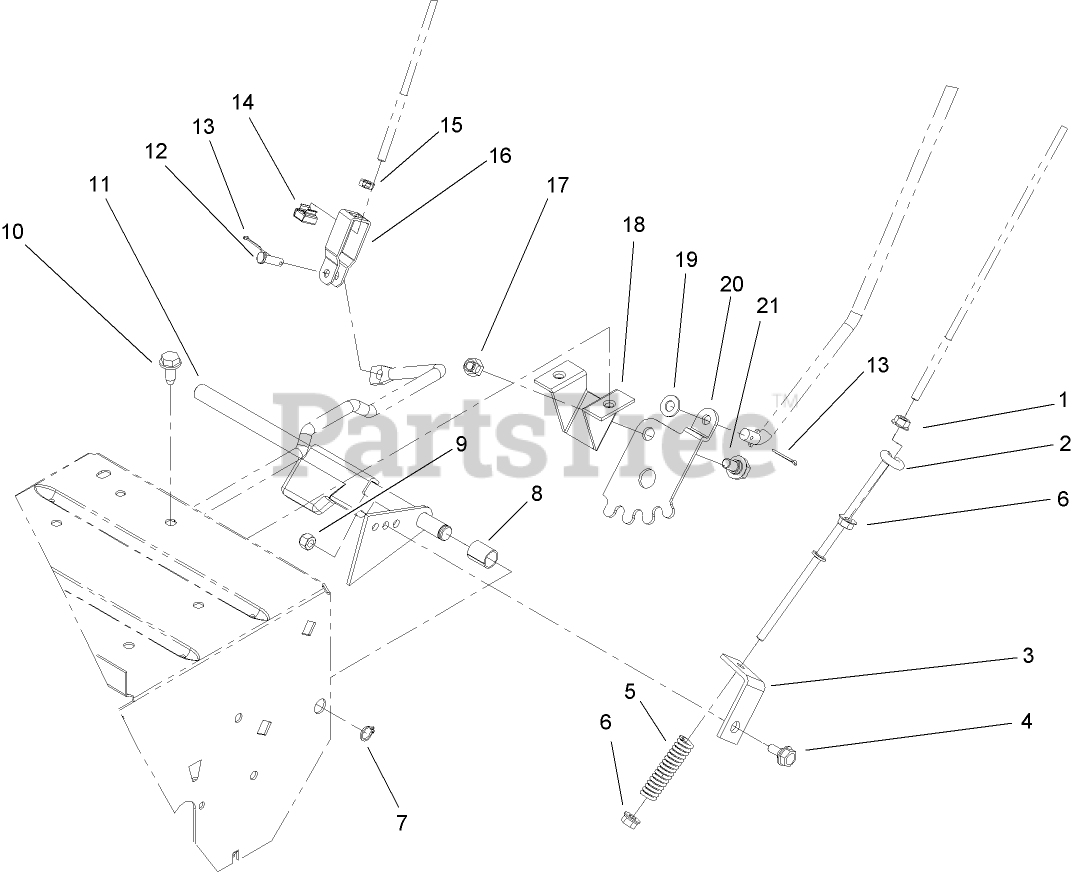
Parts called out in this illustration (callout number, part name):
1	NUT-HF
2	ROD-TRACTION, LOWER
3	BRACKET-TRACTION
4	SCREW
5	SPRING
6	NUT-HHF
7	RING-RETAINING
8	SPACER
9	NUT-LOCK, NI
10	SCREW-HWHTF
11	TRACTION ARM ASM
12	PIN-CLEVIS
13	PIN-COTTER
14	NUT-RETAINED
15	NUT-JAM
16	CLEVIS
17	NUT-LOCK, NI
18	MOUNT-LEVER
19	WASHER-PLAIN
20	GEAR-QUADRANT
21	BOLT-SHOULDER
